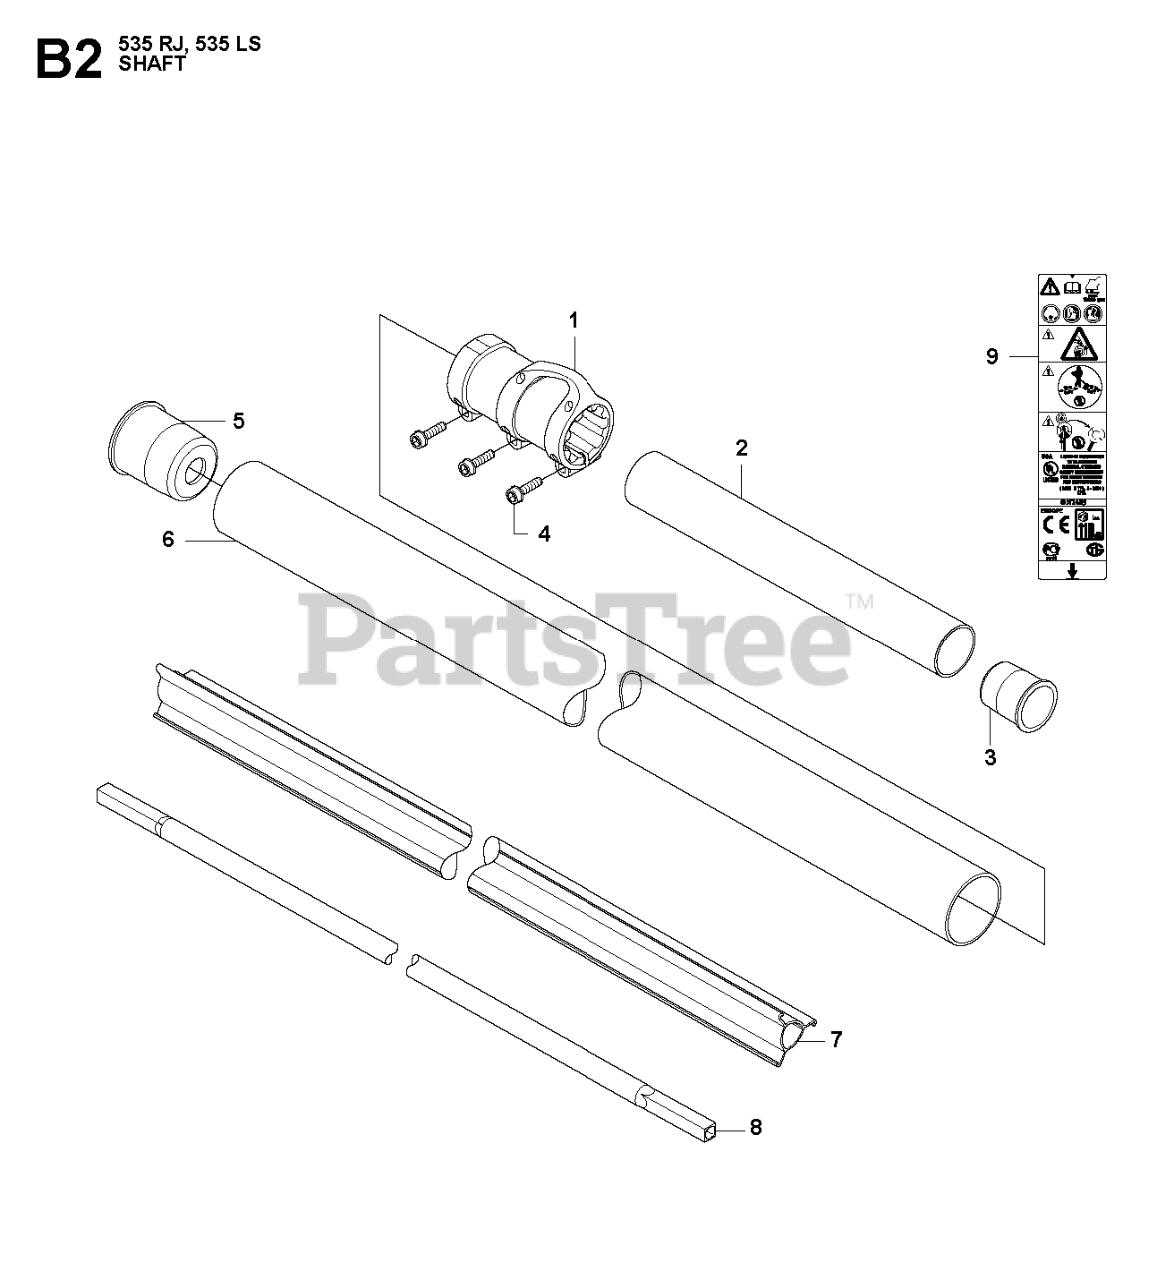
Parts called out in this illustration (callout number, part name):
1	SLEEVE
2	TUBE
3	SPACER SLEEVE
6	TUBE
7	GUIDE
8	SHAFT
9	LABEL WARNING TRIMMERS AND BRU
